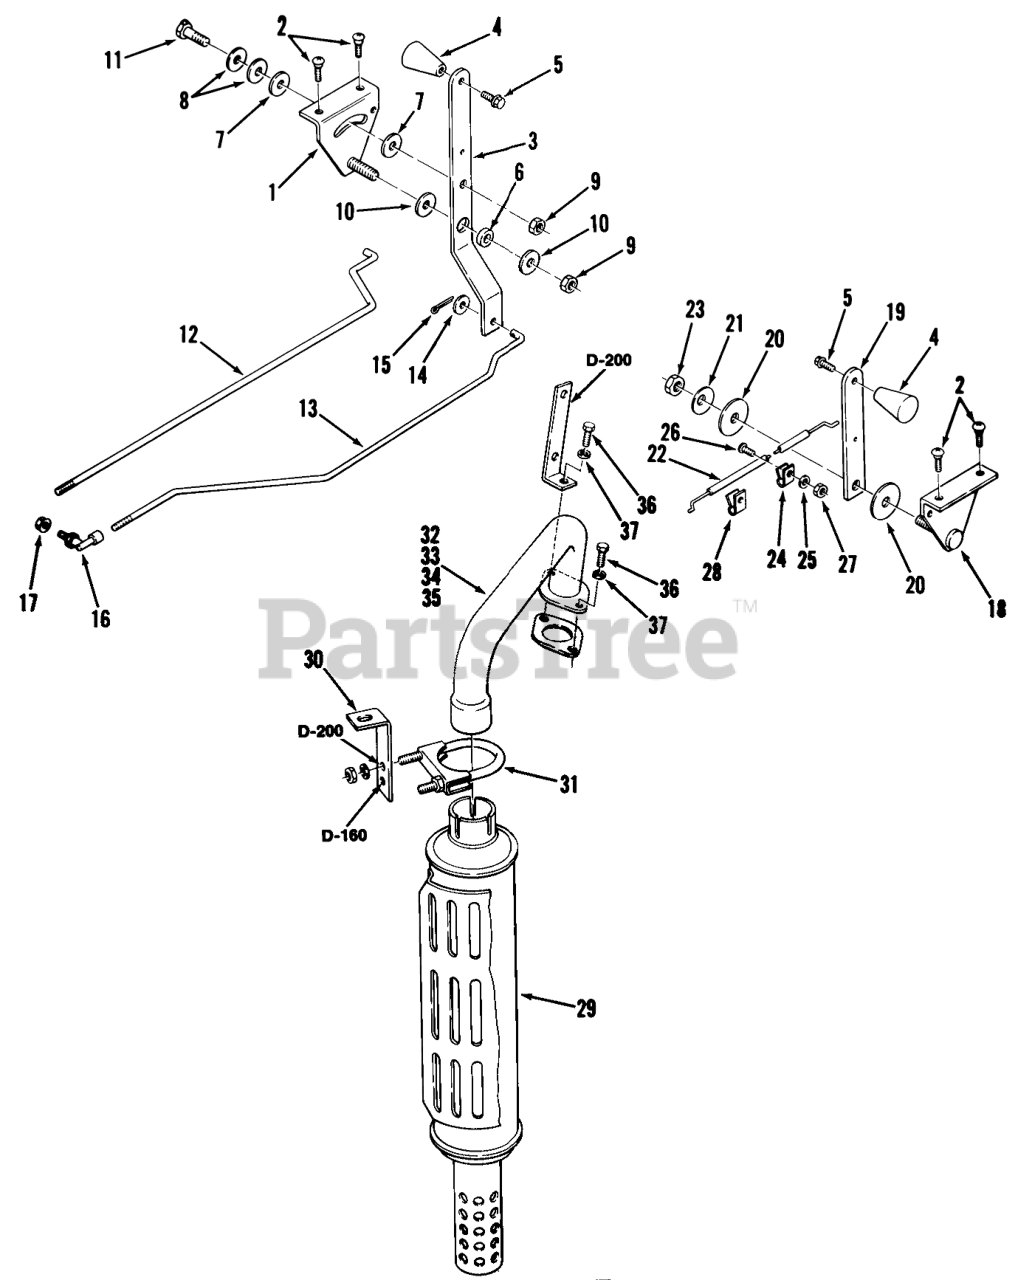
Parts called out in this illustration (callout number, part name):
6	SPACER CLUTCH ARM
7	FRICTION WASHER
8	WASHER-SPRING DISC
10	Washer-3/8
19	HANDLE
20	FRICTION WASHER
21	WASHER-SPRING DISC
24	CLIP BOWDEN WIRE
27	HEX NUT 10-32 E.S. + + USE 3296-21 + +
28	THROTTLE CONTROL CLP
31	ASSY-MUFFLER CLAMP
